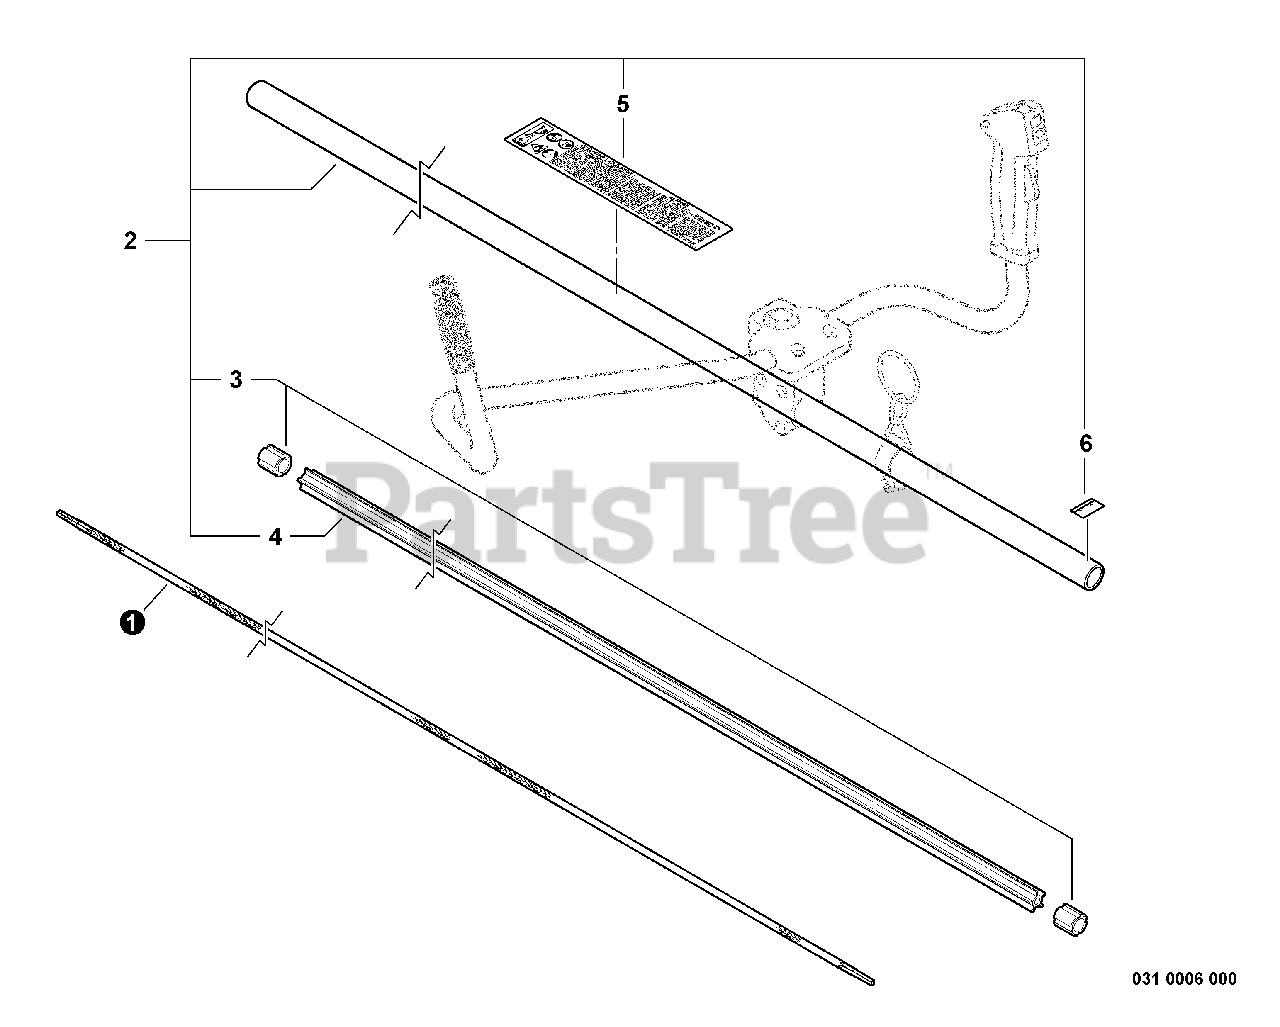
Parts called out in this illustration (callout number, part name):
1	DRIVESHAFT - FLEXIBLE
2	MAIN PIPE ASSY
4	LINER - FLEXIBLE
5	LABEL - CAUTION -- SPANISH
6	LABEL - ALIGNMENT
